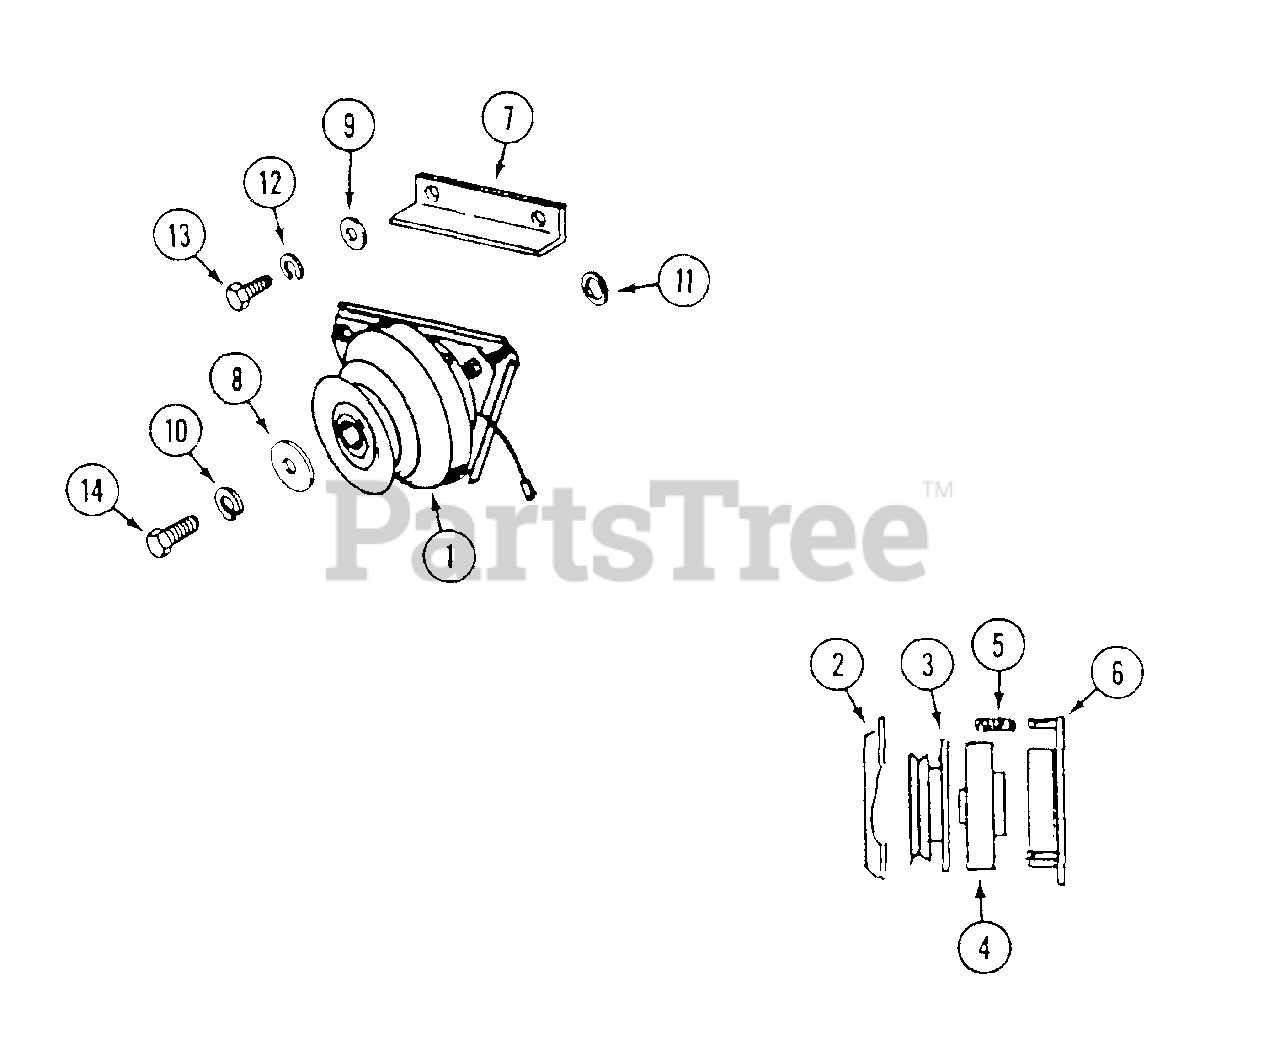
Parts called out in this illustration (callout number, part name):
1	CLUTCH ASSEMBLY
2	BRAKE - clutch
3	ARMATURE - clutch
4	ROTOR - clutch
5	KIT - spring and nut (3 each)
6	COIL - clutch
7	BRACKET - clutch stop
8	WASHER - retaining
9	WASHER - .438" x 1"
10	LOCKWASHER - 3/8"
11	WASHER - 1-1/8"
12	LOCKWASHER - 7/16"
13	BOLT - 7/16" - 14 x 3/4"
14	BOLT - 3/8" - 24 x 1-1/2"
